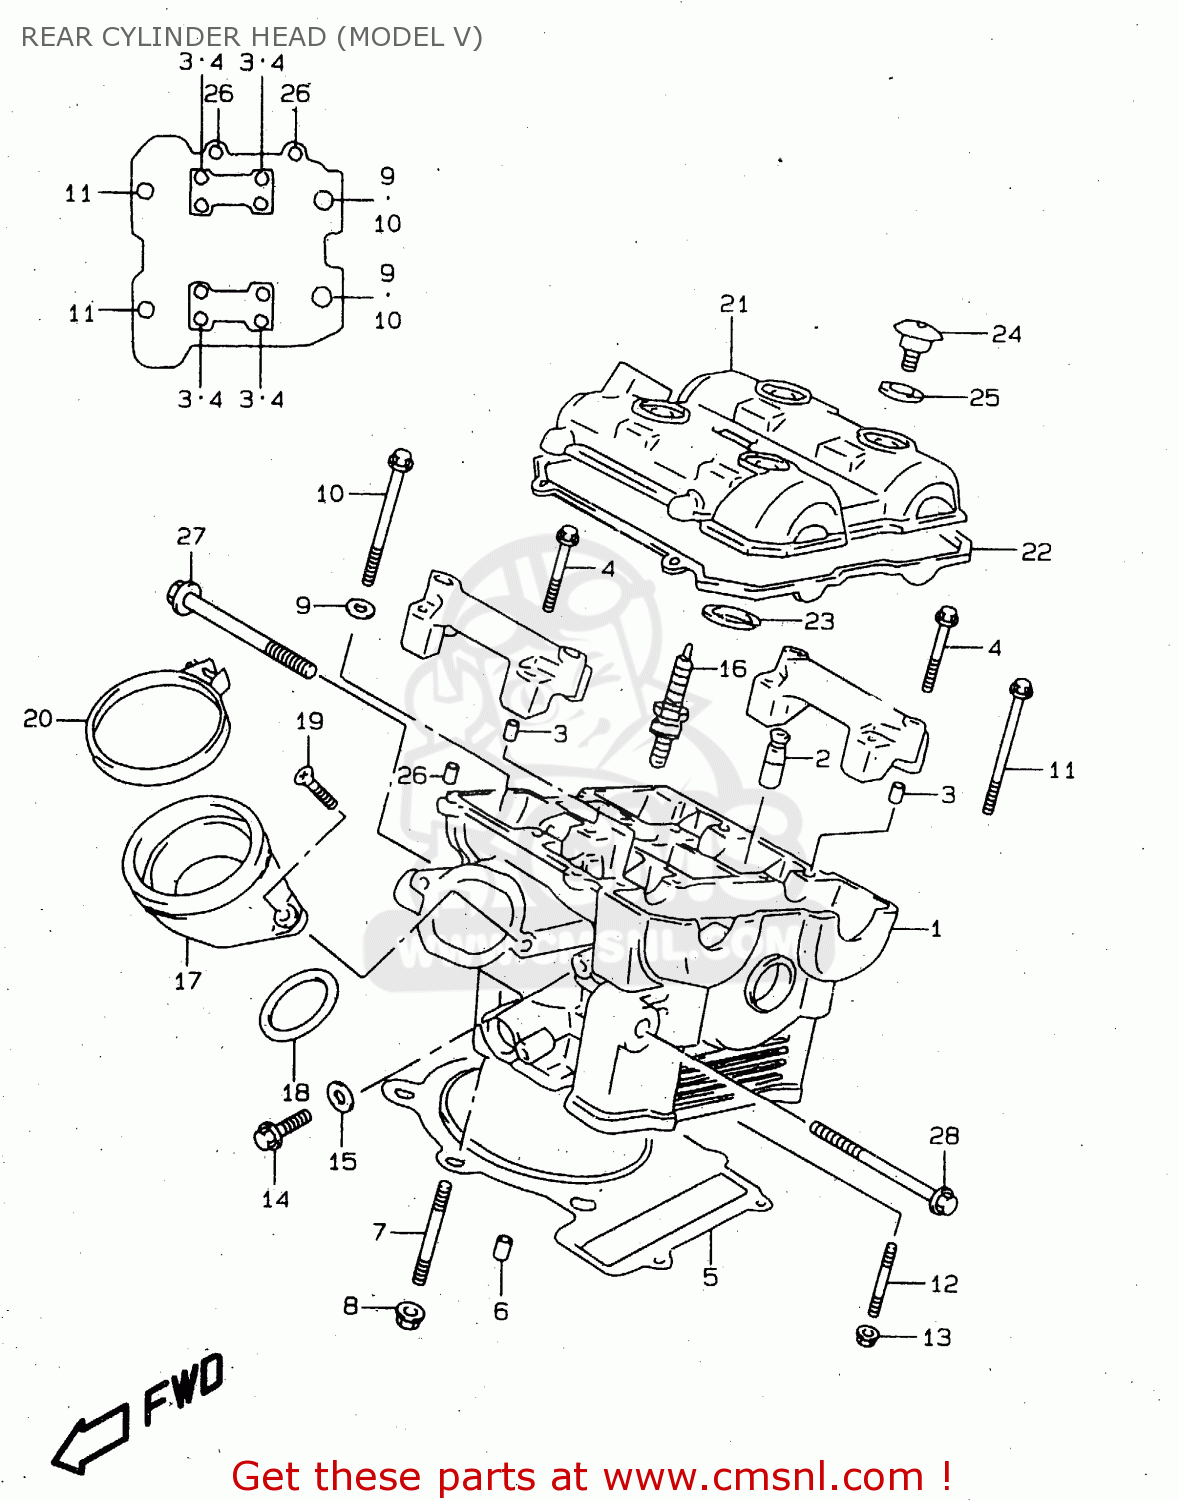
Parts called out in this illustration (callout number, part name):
1	HEAD ASSEMBLY,CYLINDER
2	GUIDE,VALVE
3	PIN(6.2X8X11)
4	BOLT(6X39)
5	GASKET,CYLINDER HEAD,FRONT (NAS)
6	PIN
7	BOLT,STUD
8	NUT
9	WASHER(10.5X19X2)
10	BOLT(10X175)
11	BOLT(6X70)
12	BOLT,STUD
13	NUT
14	BOLT
15	GASKET(5.8X13X1.2) (NAS)
16	PLUG,SPARK(CR8E)
17	PIPE ASSY,INTAKE
18	O RING(D:2.4,ID:55.6)
19	SCREW
20	CLAMP
21	COVER,CYLINDER HEAD,REAR
22	GASKET,CYL HEAD COVER NO.1 (NAS)
23	GASKET,CYL HEAD COVER NO.2
24	BOLT(7X17.5)
25	WASHER(10.6X25.5X2.3)
26	PIN(6.2X8X11)
27	BOLT
28	BOLT
